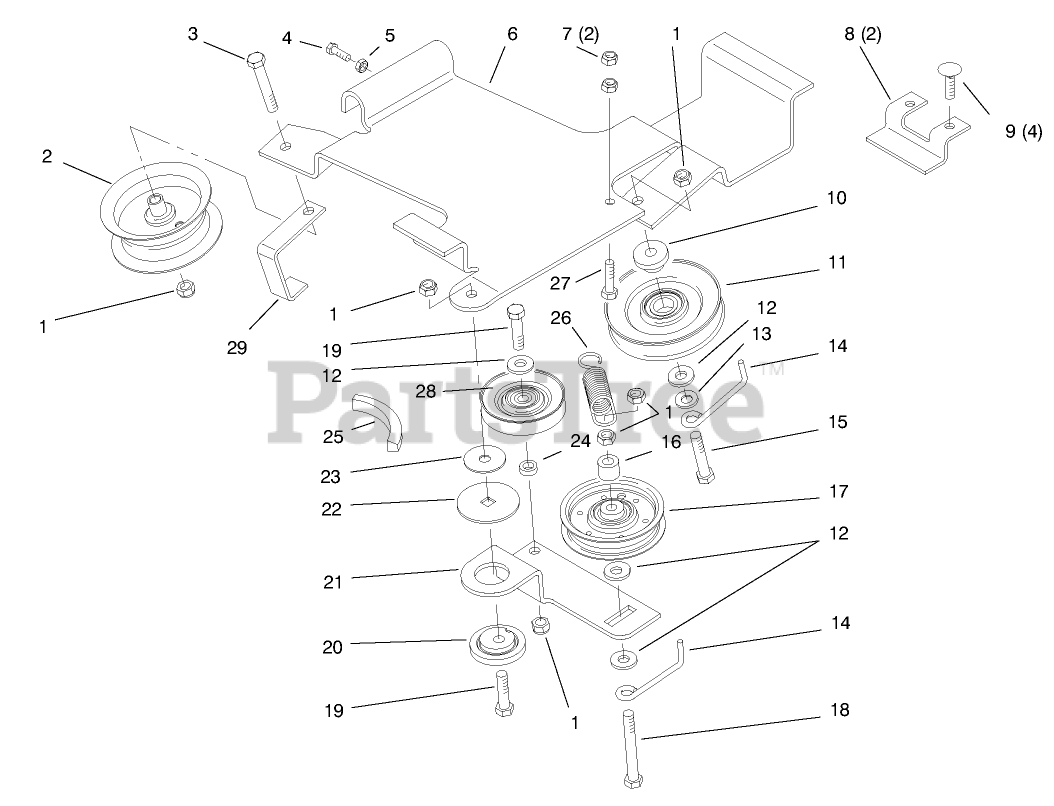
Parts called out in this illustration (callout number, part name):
1	NUT-LOCK, NI
2	IDLER
3	SCREW-HH
4	SCREW-HEX HD
5	NUT-JAM
6	RACK-TILLER DRIVE
7	NUT-LOCK, NI
8	BRACKET - RACK MOUNTING
9	BOLT-CARR
10	SPACER
11	PULLEY-IDLER
12	WASHER-SPACER
13	WASHER-FLAT
14	GUIDE-BELT
15	SCREW-HH
16	SPACER-PIVOT
17	PULLEY-IDLER, FLAT
18	SCREW-HH
19	SCREW-HH
20	BUSHING
21	ARM-IDLER
22	WASHER-BEARING
23	WASHER
24	SPACER
25	V-BELT (A, 148.50" )
26	SPRING-EXTENSION
27	SCREW-HH
28	PULLEY-IDLER
